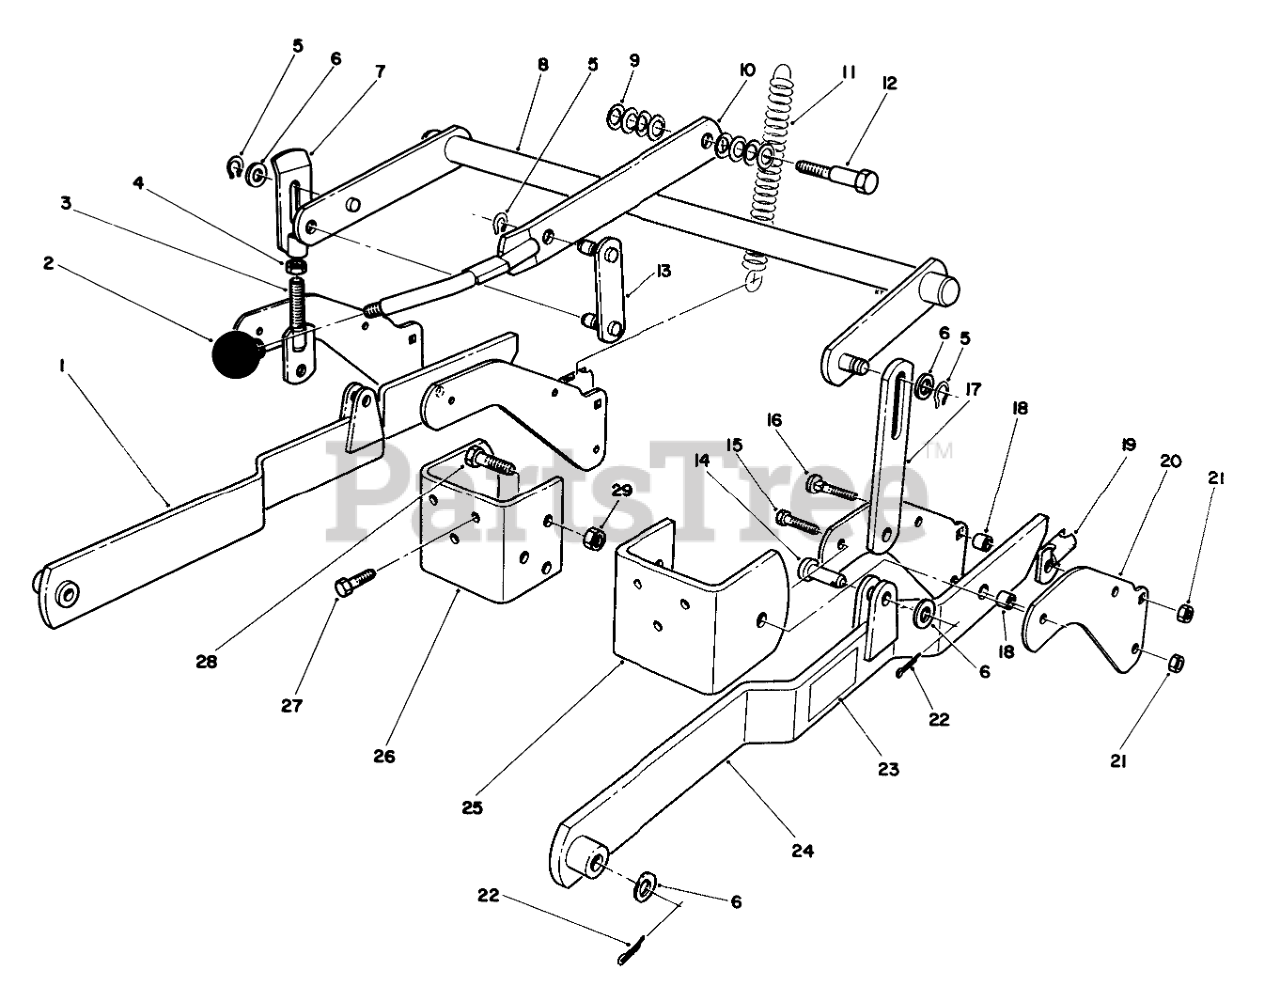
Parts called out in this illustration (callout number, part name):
1	Lift Bar-R.H. (Incl. Ref. #23)
3	HOC PLATE WA
4	NUT-JAM
5	RING-RETAINING
6	WASHER-FLAT
7	HOC LINK WA
8	HOC PIVOT ARM WA B
9	WASHER-BELLEVILLE
10	HOC LEVER WA B
11	SPRING EXT.
12	BOLT-SHOULDER
13	UPPER HOC LINK WA
14	PIN-CLEVIS
15	SCREW-HH
16	SCREW-CARR
17	SUSPENSION DECK LINK B
18	DECK LIFT SPACER
19	DECK SPRING LINK
20	REAR PIVOT ARM B
21	NUT-LOCK, NI
22	PIN-COTTER
23	DECAL-WARNING
24	Lift Bar-L.H. (Incl. Ref. #23)
25	U-BRKT DECK LIFT B
26	U-BRKT DECK LIFT B
27	SCREW-HH
28	SCREW-HH
29	NUT-LOCK, NI
